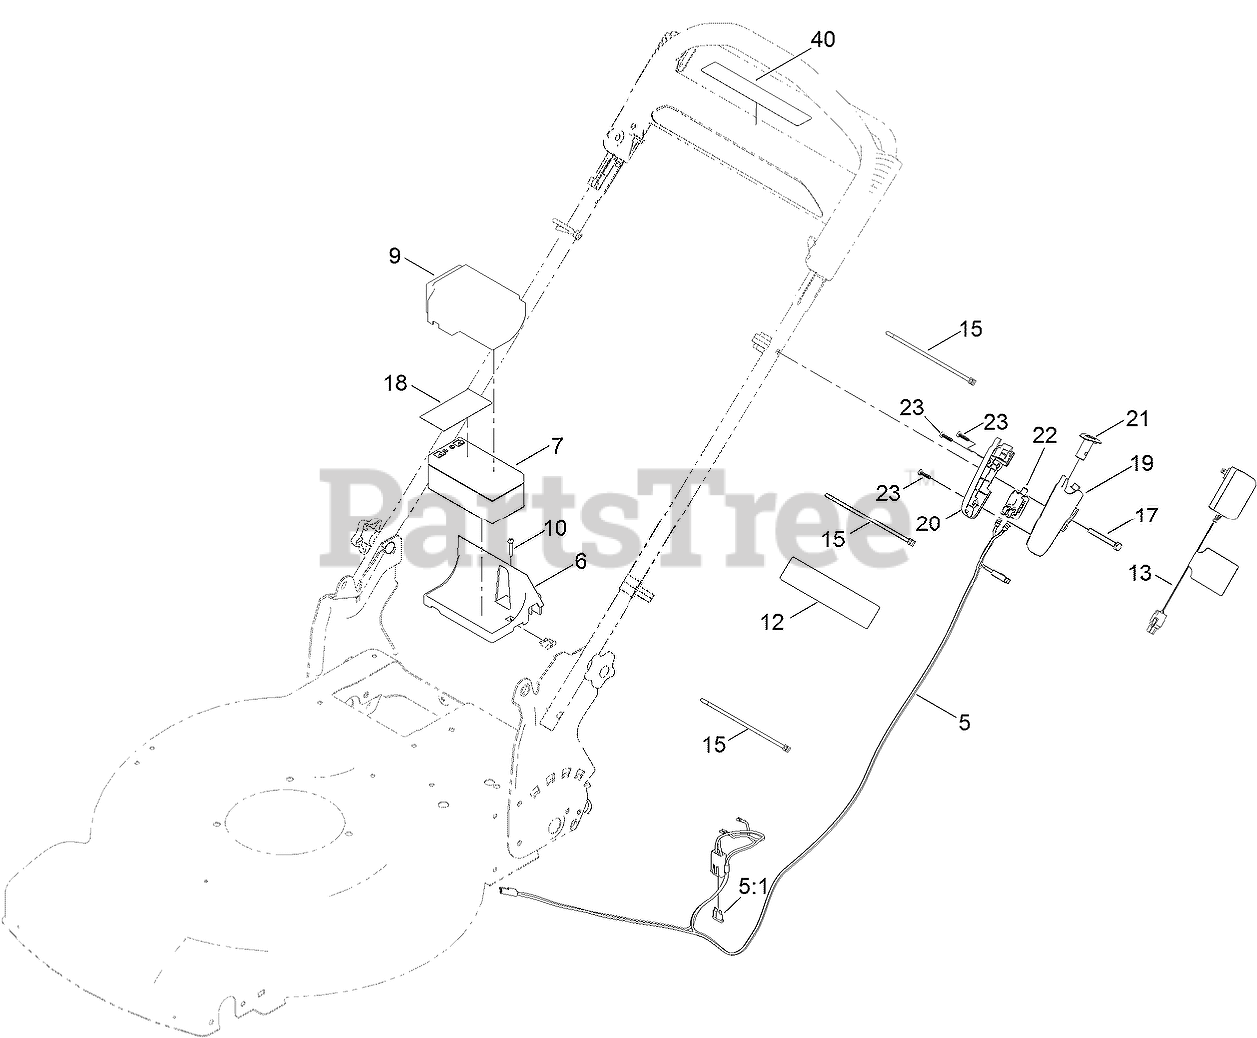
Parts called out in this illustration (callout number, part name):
5	HARNESS-WIRE
5:1	FUSE-40 AMP
6	TRAY-BATTERY
7	BATTERY-WET
9	COVER-BATTERY
10	SCREW-PLASTIC, PPH
12	DECAL-WARNING
13	CHARGER, BATTERY (12V, CE)
13	CHARGER, BATTERY (12V, UK)
15	TIE-CABLE
17	SCREW-HH
18	DECAL-TERMINAL, BATTERY
19	HOUSING-SWITCH, LH
20	HOUSING-SWITCH, RH
21	BUTTON-SWITCH
22	SWITCH-PUSH BUTTON
23	SCREW-PPH
40	DECAL-BUTTON, PUSH
